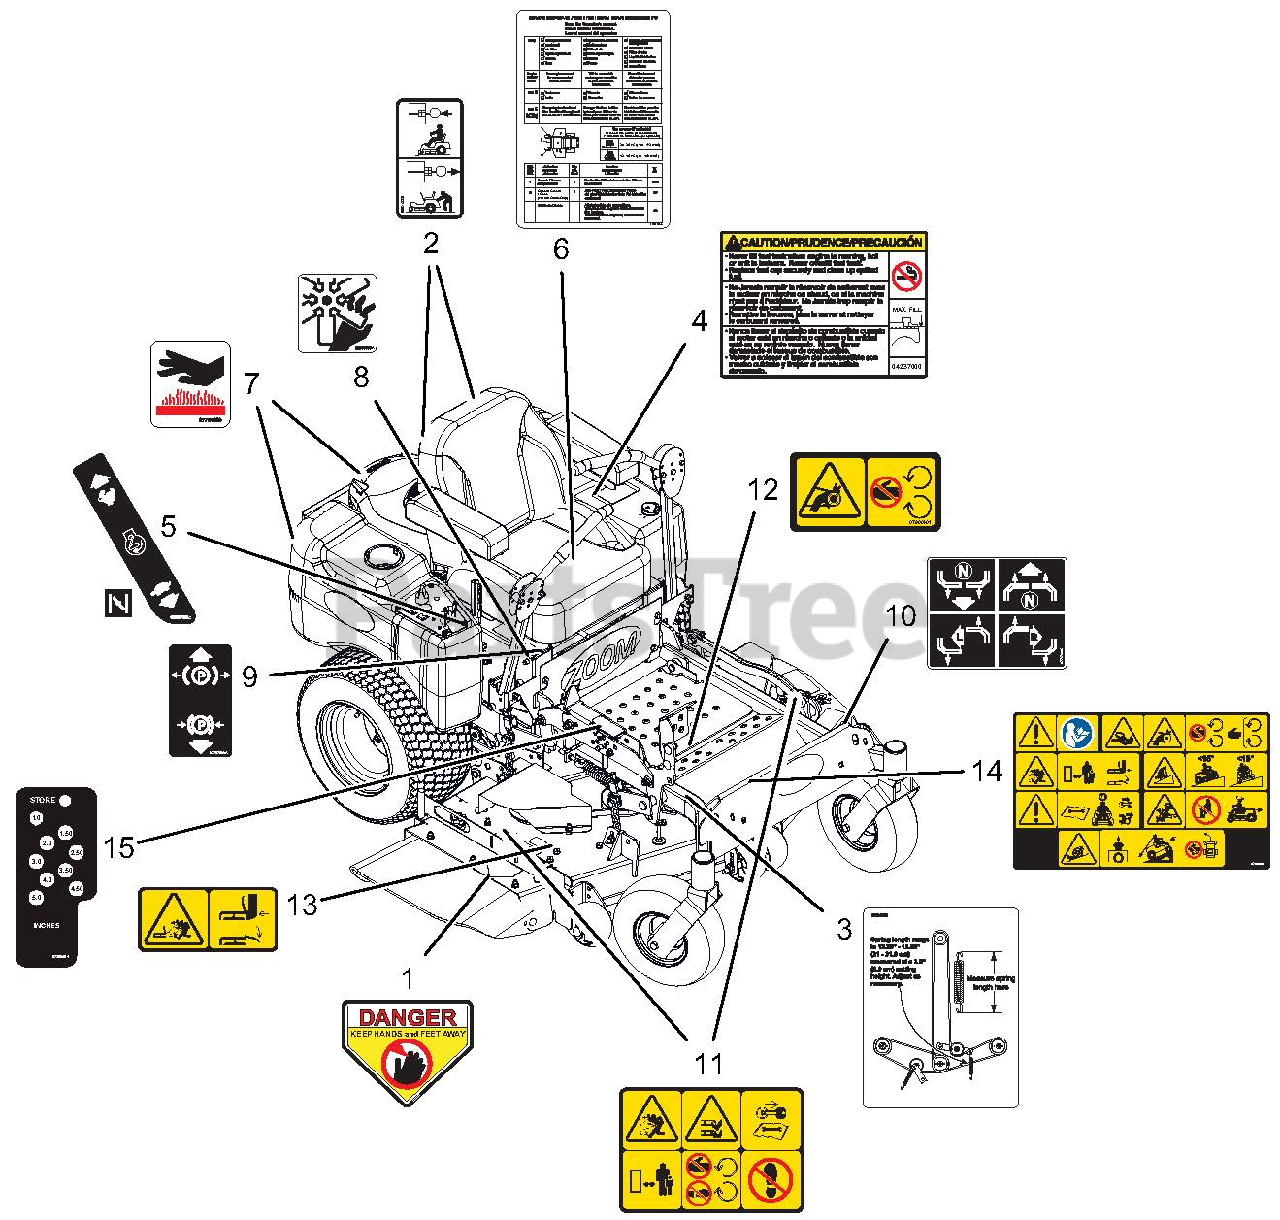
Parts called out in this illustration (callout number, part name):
1	DECAL, DANGER
2	DECAL, TRANSMISSION DISCONNECT
3	DECAL, BELT ROUTING
4	DECAL, FUEL WARNING
5	DECAL, SPEED CONTROL
6	DECAL-MAINTENANCE INSTRUCTIONS
7	DECAL, HOT SURFACE
8	DECAL, DANGER FAN
9	DECAL, PARKING BRAKE LEVER
10	DECAL, INSTRUCTIONAL-STEERING
11	DECAL, SAFETY - MOWER DECK
12	DECAL, SAFETY - GUARDING
13	DECAL, SAFETY - DECK GUARDING
14	DECAL, MAIN SAFETY
15	DECAL, HD HEIGHT OF CUT
